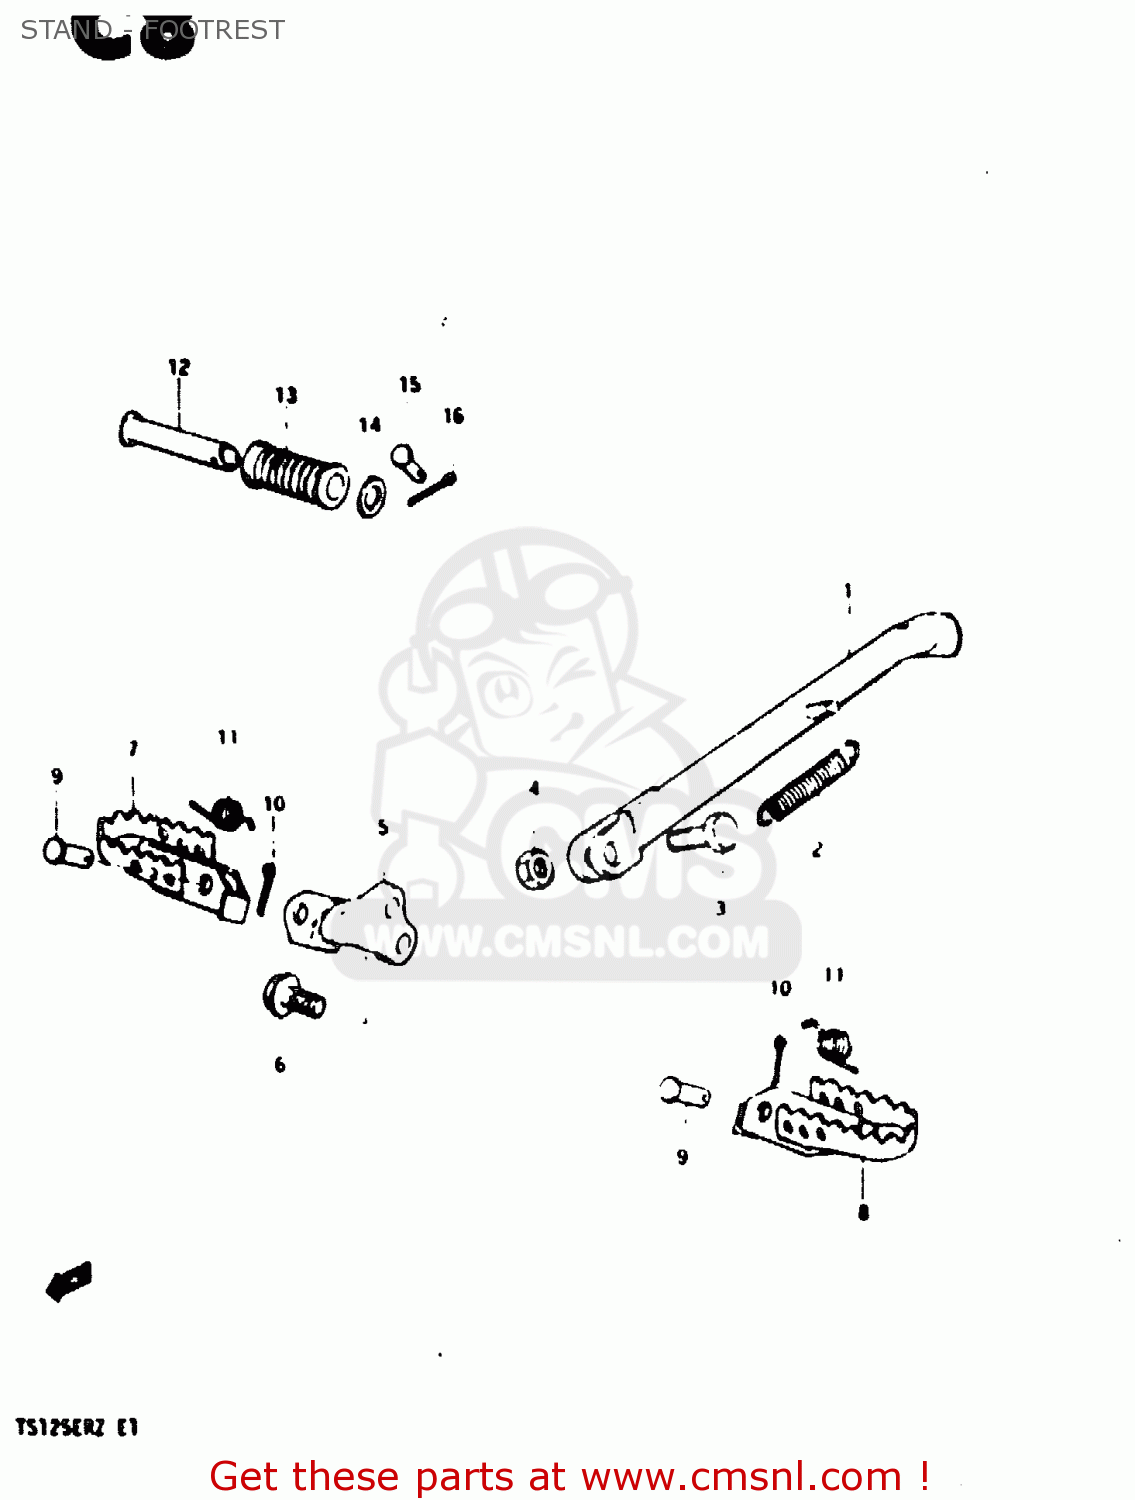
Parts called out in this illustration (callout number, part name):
1	STAND,SIDE
2	SPRING
3	BOLT(10X30)
4	NUT
5	HOLDER,FR FOOTREST,R
6	BOLT
7	FOOTREST,FRONT
8	FOOTREST,FRONT,LEFT
9	PIN
10	PIN 20X20
11	SPRING
12	BAR,PILLION FOOTREST
13	RUBBER,PILLION FOOTREST
14	WASHER (19.5X32X2)
15	PIN
16	PIN 20X20
